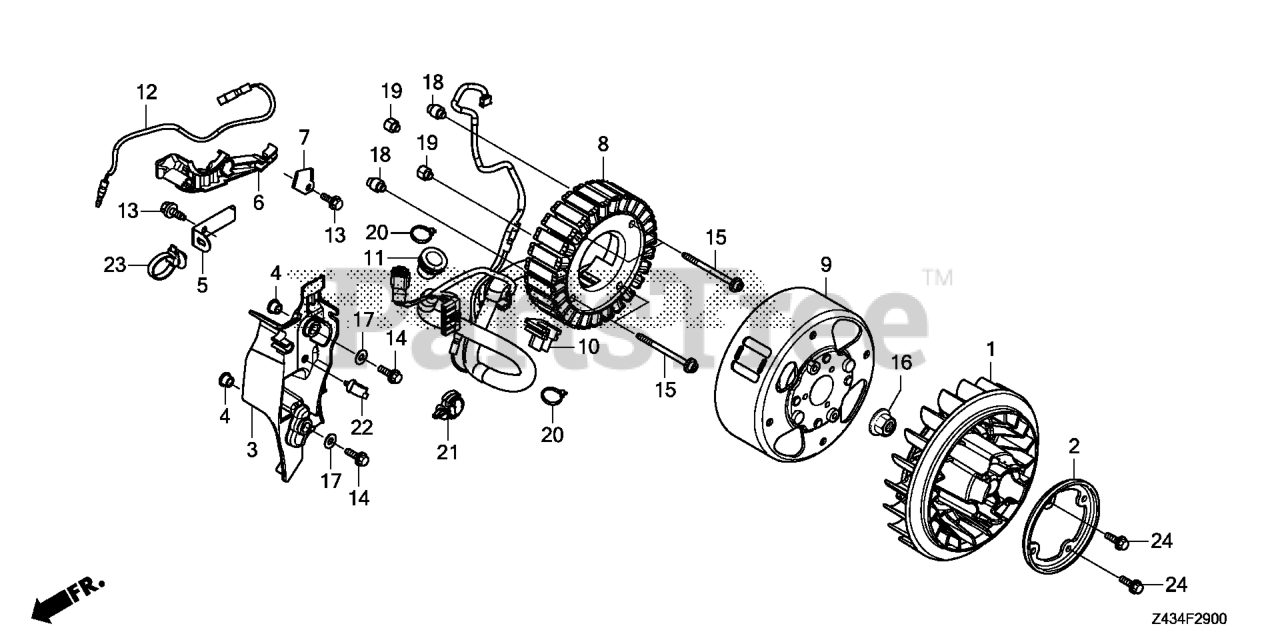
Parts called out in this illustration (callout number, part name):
1	FAN, COOLING
2	PLATE, COOLING FAN
3	PLATE B, SIDE *NH1* (BLACK)
4	COLLAR, SIDE PLATE
5	STAY, CLIP
6	PROTECTOR, GENERATOR HARNESS
7	CLAMP, WIRE
8	STATOR ASSY.
11	GROMMET, UNIT SWITCH
12	WIRE, OIL LEVEL SWITCH
13	BOLT, FLANGE (6X14)
14	BOLT, FLANGE (6X20) (CT200)
15	BOLT, FLANGE SOCKET (6X61) (CT200)
16	NUT, SPECIAL (14MM)
17	WASHER (6.5X15)
18	COLLAR, STATOR
19	COLLAR, STATOR
20	TIE, CABLE
21	CLIP, WIRE HARNESS
22	CLIP, WIRE HARNESS
23	CLIP, WIRE HARNESS
24	BOLT, FLANGE (6X16) Use from Engine SN 2056820.
